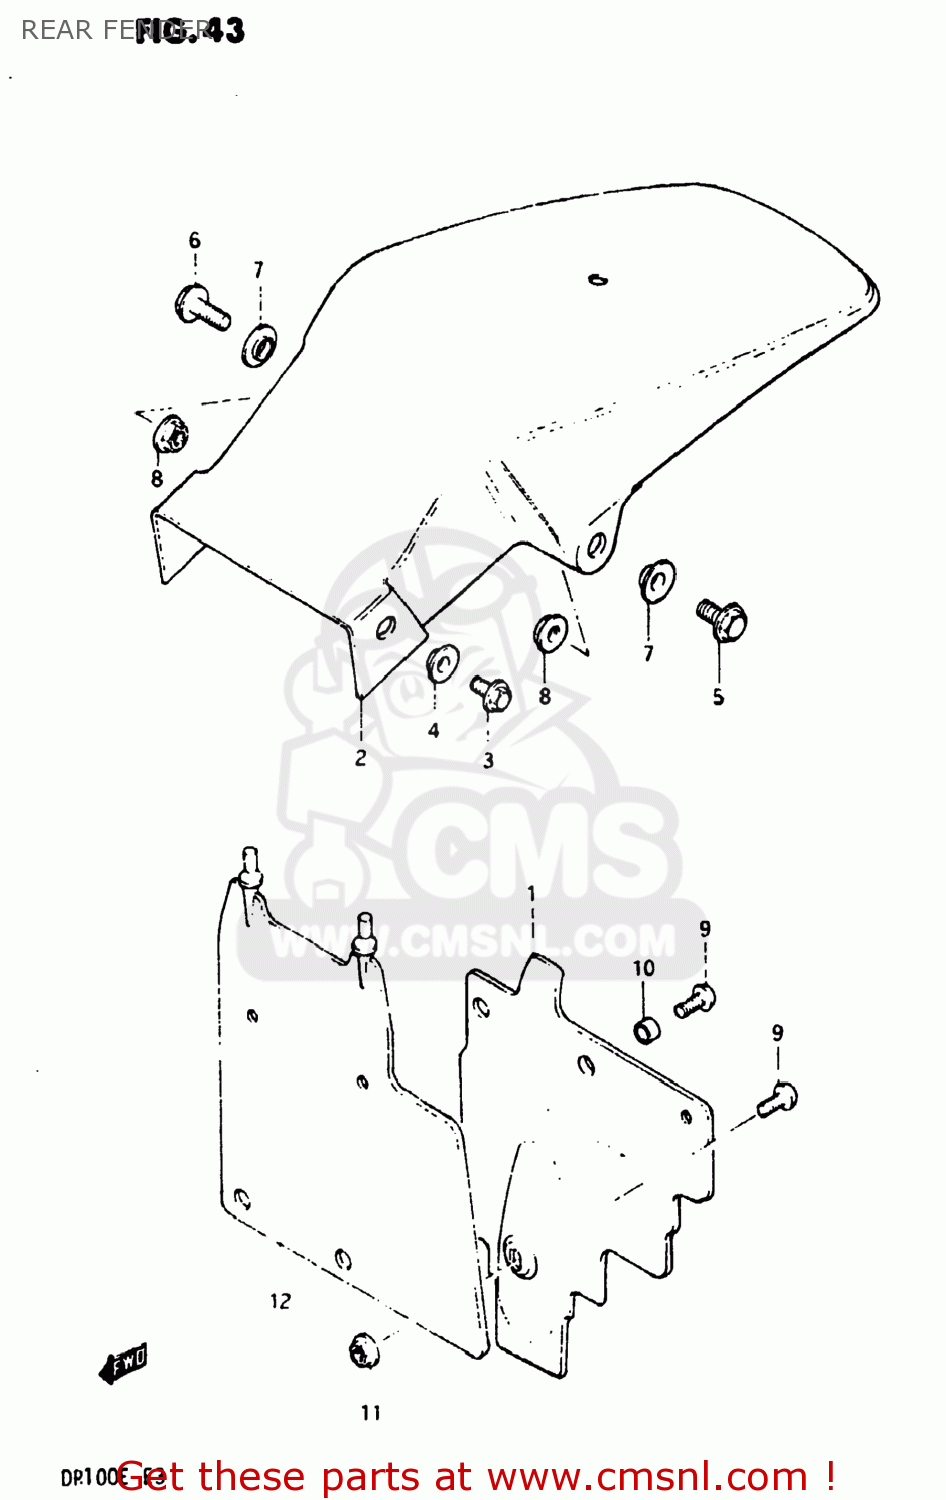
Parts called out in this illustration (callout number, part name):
1	FENDER, RR FR
2	FENDER,REAR
3	BOLT
4	WASHER
5	BOLT
6	BOLT
7	WASHER
8	NUT
9	SCREW, FRONT
10	SPACER
11	NUT
12	MUD GUARD,REAR FENDER
